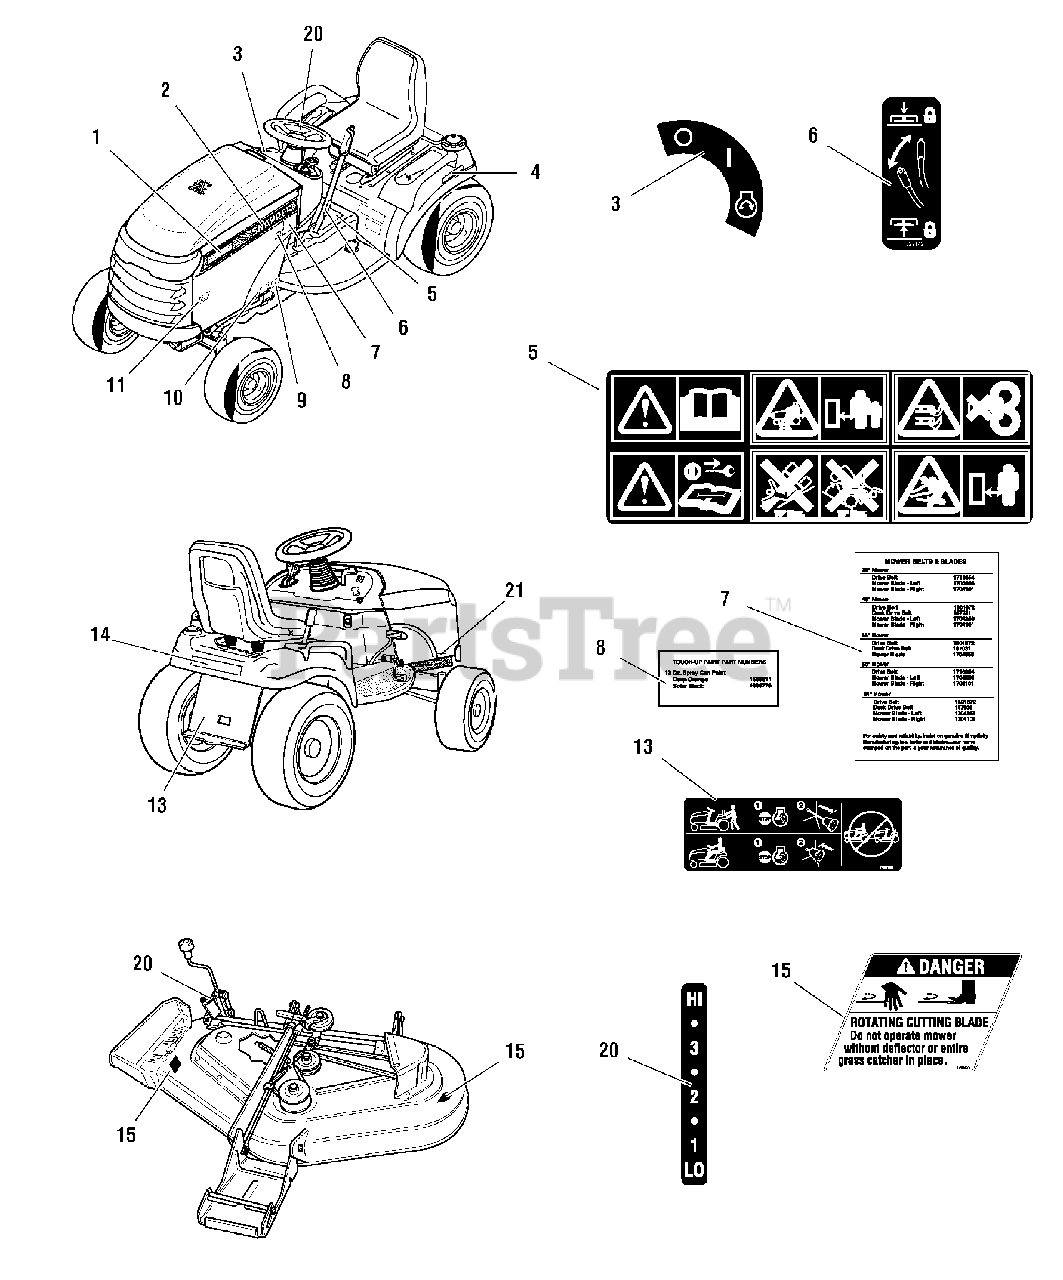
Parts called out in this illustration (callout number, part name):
1	DECAL, YT400 23HP
2	DECAL, Hood Stripe, Snapper, LH
2	DECAL, Hood Stripe, Snapper, RH
3	DECAL, Ignition Switch Symbols, White/Black
4	DECAL, Automatic Control Traction
5	DECAL, Tunnel Cover
6	DECAL, Lift Lever Symbols
7	DECAL, Drive Belts, Mower Blades
8	DECAL, Touch-Up Paint, Red
9	DECAL, Protective Sticker
10	DECAL, Power Steering
11	DECAL, 4x4
13	DECAL, Transmission Release Valve
14	DECAL, Snapper w/stripe
15	Decal, Rotating Blade
17	DECAL, OPEI Certified
20	DECAL, Snapper Icon
21	DECAL, Patent
21	DECAL, Height of Cut
